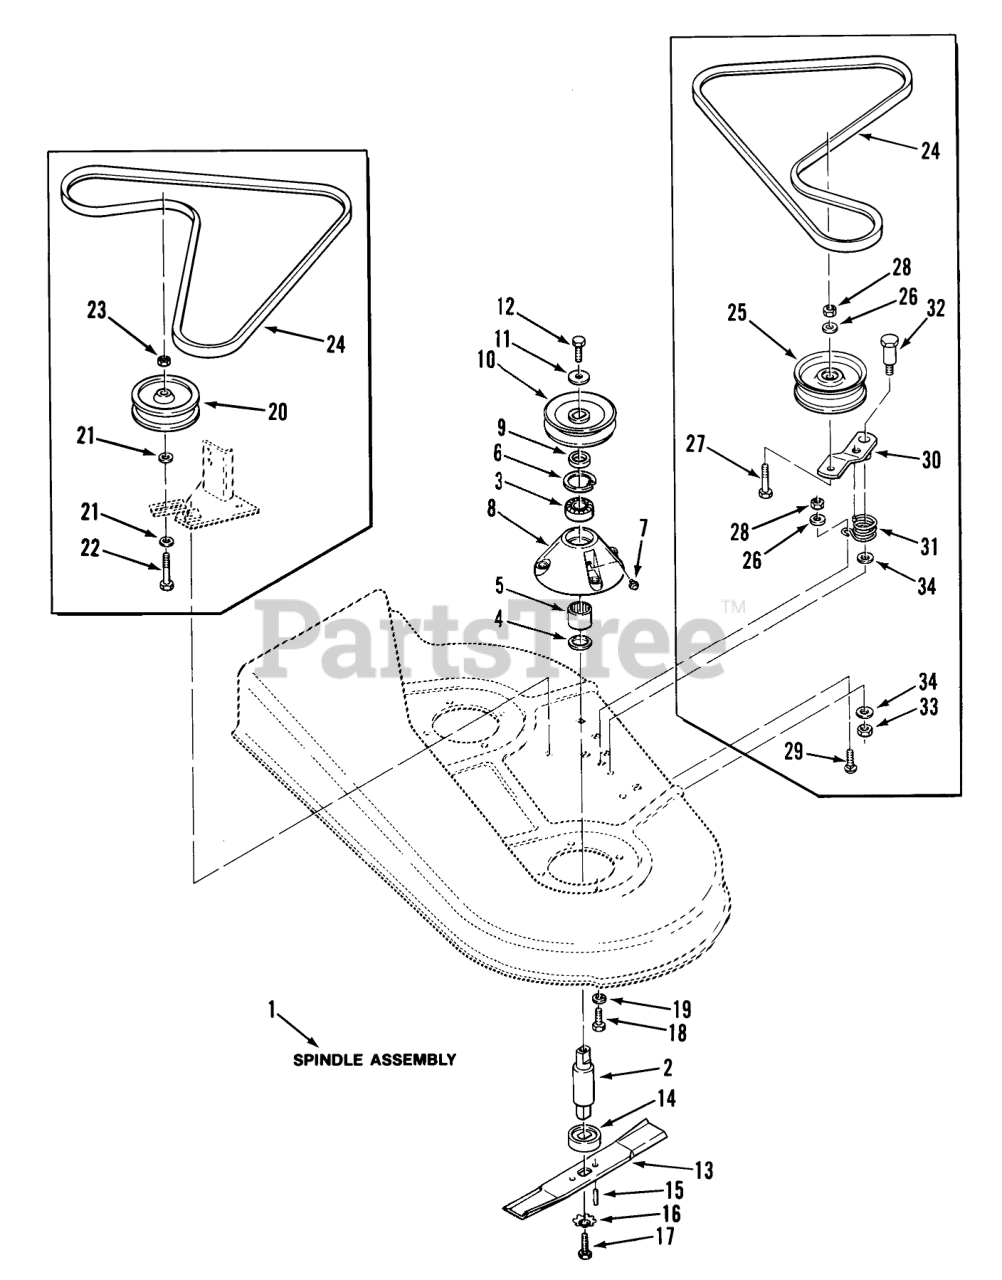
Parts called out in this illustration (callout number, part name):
3	BEARING-BALL
4	OIL SEAL
5	BEARING-NEEDLE
6	INT SNAP RING
8	HOUSING
9	SPACER
11	WASHER
13	S/A BLADE KIT
15	SPIROL ROLL PIN
25	PULLEY-IDLER
31	SPRING-TORSION
34	WASHER
